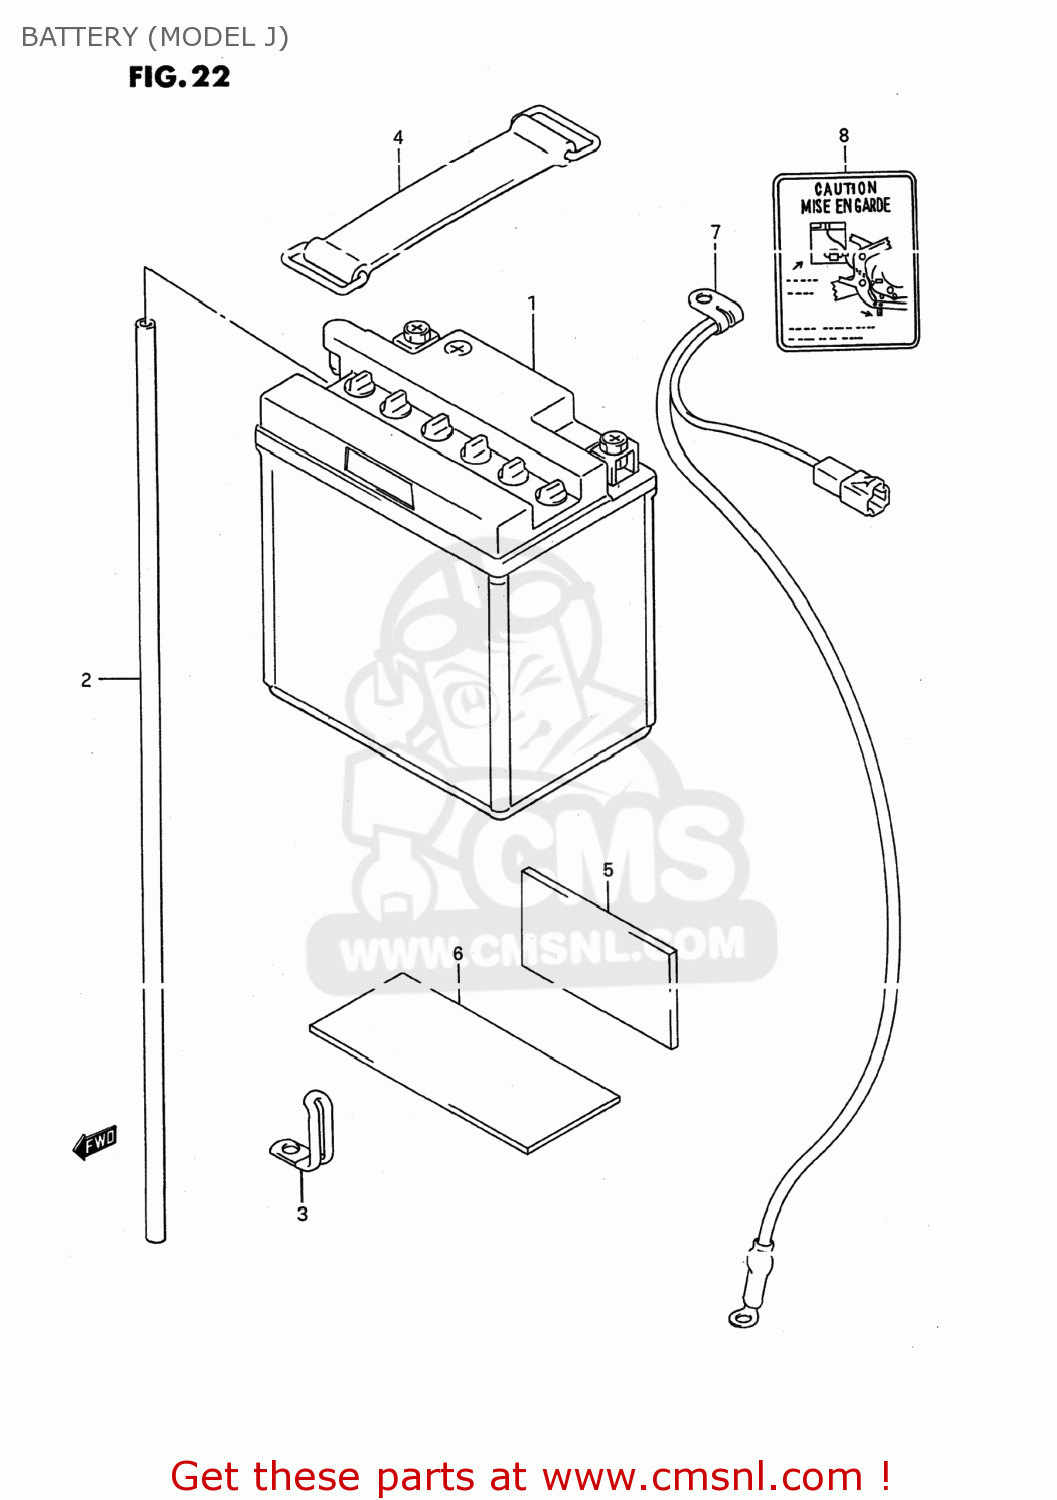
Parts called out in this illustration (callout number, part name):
1	BATTERY(YB10L-B2,12V11.6AH)
2	HOSE,BATTERY EXHAUST
3	CLAMP(L:35)
4	BAND
5	PROTECTOR,20X9
6	PROTECTOR(170X95X3.0)
7	WIRE,BATTERY MINUS LEAD
8	PLATE,BATTERY CAUTION
